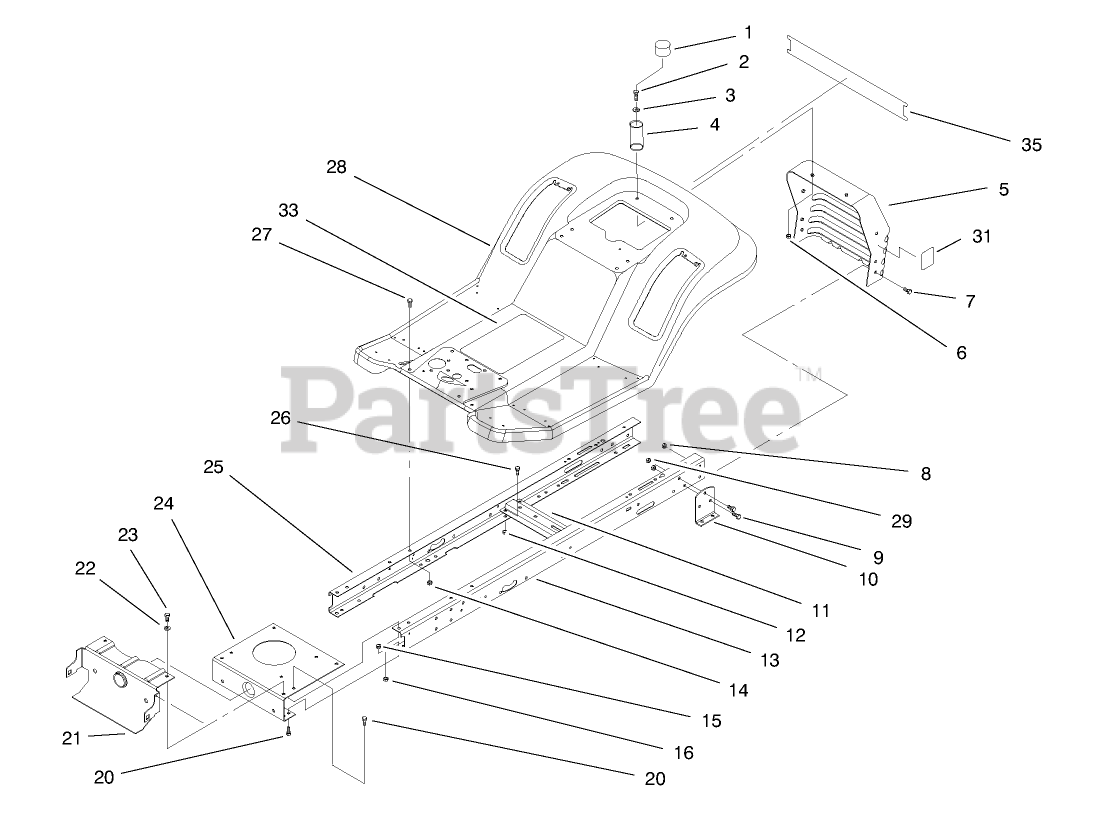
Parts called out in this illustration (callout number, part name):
1	CAP-PROTECTOR
2	SCREW-HH
3	WASHER-PLAIN
4	SPRING-COMPRESSION
6	NUT-LOCK, NI
7	SCREW-HH
8	NUT-LOCK, NI
9	SCREW-HH
10	BRACKET-TRANSAXLE, MOUNTING
11	BRACKET-IDLER PIVOT
12	NUT-LOCK, NI
14	NUT-LOCK, NI
15	NUT-LOCK, NI
16	NUT-LOCK, NI
20	SCREW-HH
22	WASHER-PLAIN
23	SCREW-HH
24	PLATE-MOUNTING, ENGINE
26	SCREW-HH
27	SCREW-HH
29	NUT-LOCK, NI
33	DECAL-INSTRUCTION
35	DECAL-REAR BODY 1438 HXL
